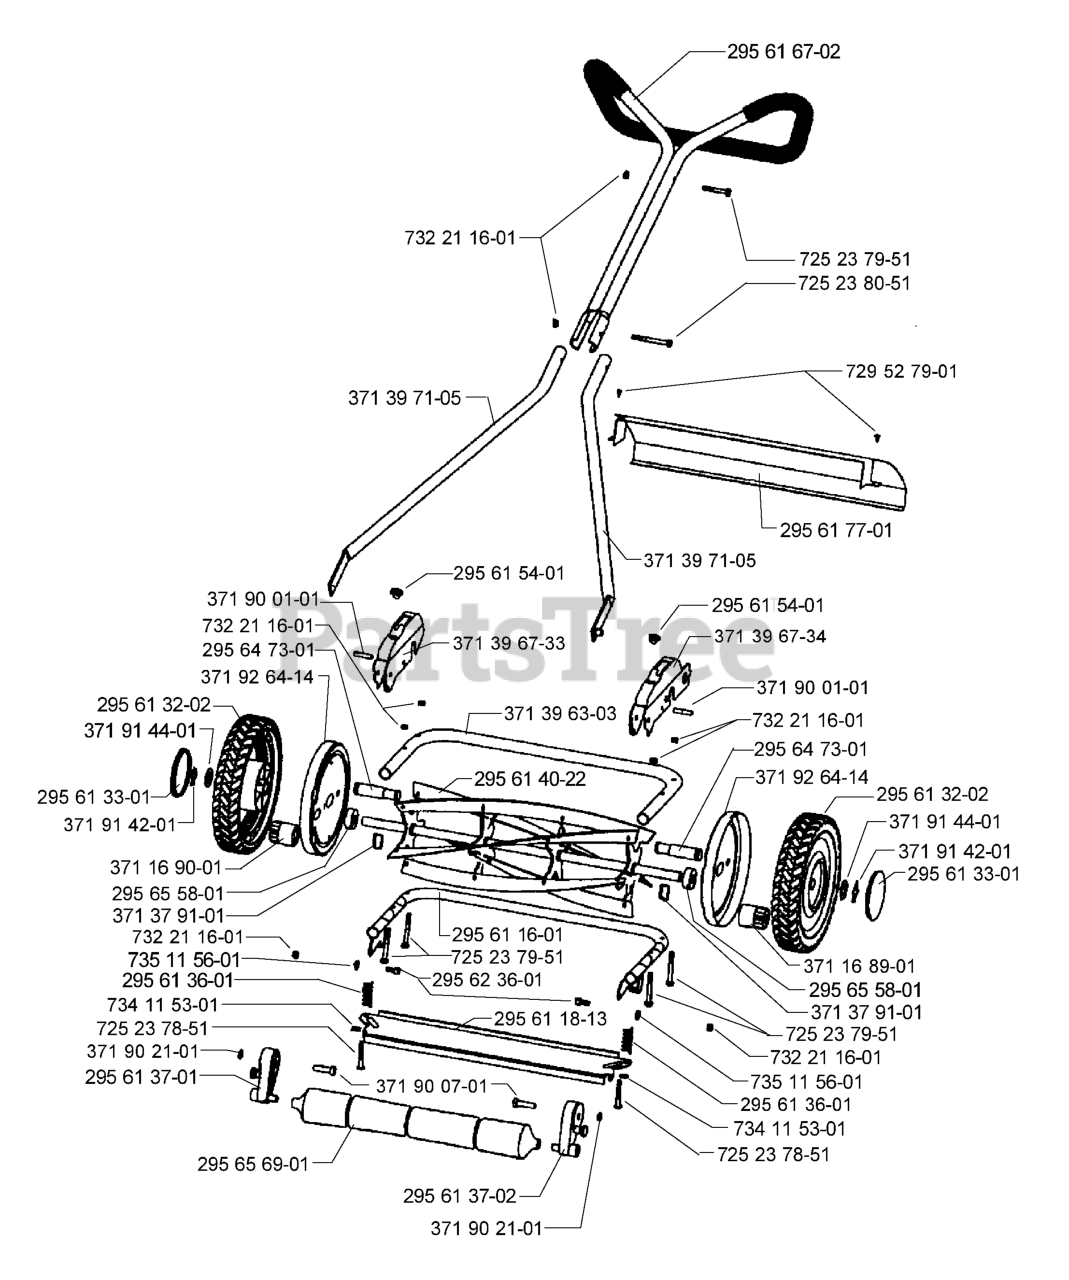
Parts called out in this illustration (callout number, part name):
1	CONTROL BAR
2	UPPER HANDLE
3	HANDLE, LOWER PM
4	ROPE GUIDE
5	NUT
6	HANDLE BOLT
7	SCREW 1/4-20 X 2.12
8	WASHER
10	CABLE.MZR.51.RT.SP./PU.
11	TAPPING SCREW
12	BRACKET UPSTOP
15	NUT WING PM
16	TIE GUIDE
17	HAIRPIN COTTER
18	GUARD-DISCHARGE
20	HANDLE BRKT ASSY LH
21	HANDLE BRKT ASSY RH
22	WASHER.BELLEVILLE (3 2 LB)
23	Wheel & Tire Assembly 7.0 x 1-1/2
24	BOLT
25	BOLT
26	STEEL WASHER
27	SCREW
